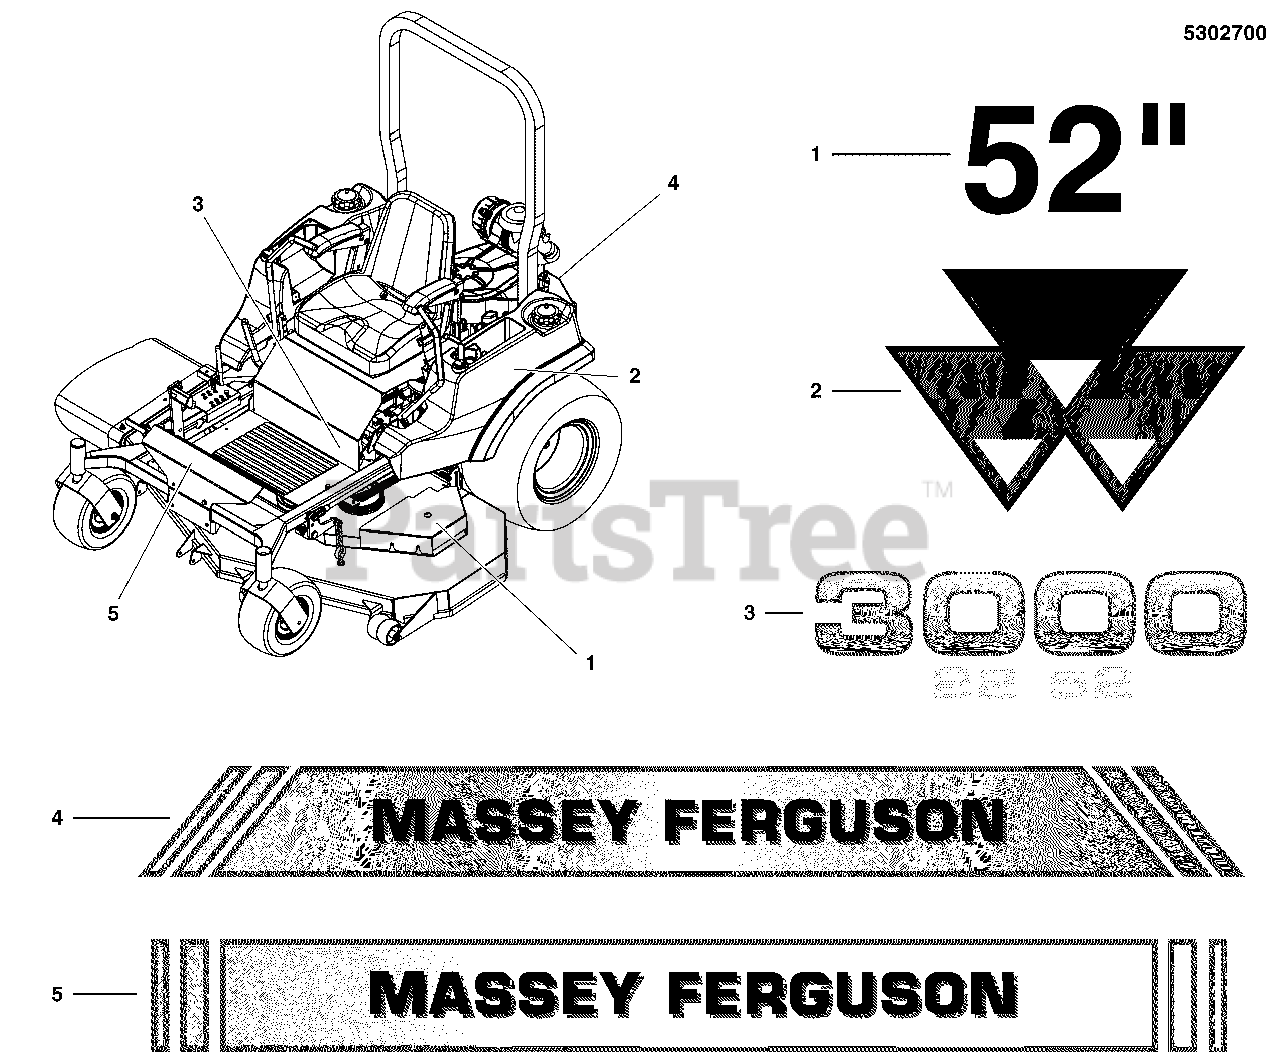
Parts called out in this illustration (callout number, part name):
1	DECAL, 52
2	DECAL, MASSEY LOGO SIDE PANEL
3	DECAL, 3000 22/52 MODEL NAME
4	DECAL, MASSEY LOGO BACK
5	DECAL, MASSEY, FRONT, 3000
